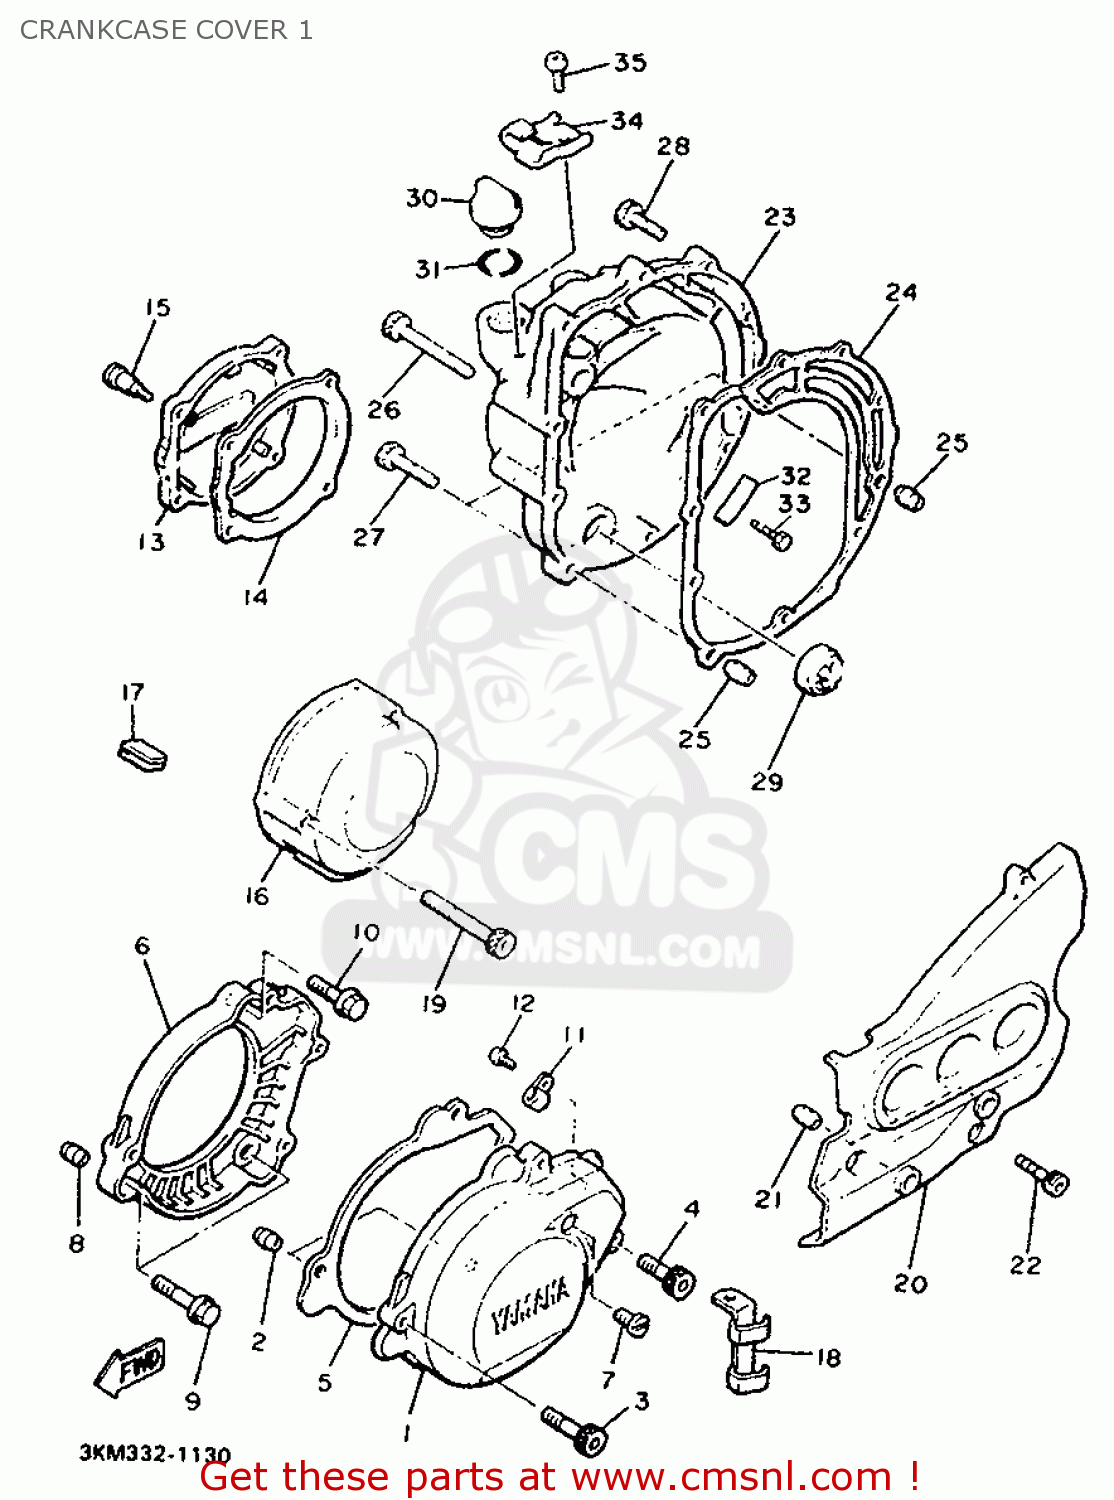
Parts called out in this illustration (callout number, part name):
01	COVER, GENERATOR
02	P1N, DOWEL
03	BOLT
04	BOLT
05	GASKET, CRANKCASE COVER 1 (MCA)
06	COVER, GENERATOR 2
07	PLUG, STRAIGHT SCREW(3KM)
08	P1N, DOWEL
09	BOLT, WASHER BASED(3KM)
10	BOLT, WASHER BASED(3KM)
11	CLAMP(3KM)
12	SCREW PAN HEAD
13	COVER, OIL PUMP 2
14	RING, RUBBER
15	BOLT 1
16	COVER, GENERATOR
17	GROMMET(3KM)
18	CLAMP(3LT)
19	BOLT
20	COVER, CRANKCASE 1
21	PIN, DOWEL
22	BOLT
23	COVER, CRANKCASE 2
24	GASKET, CRANKCASE COVER 2 (MCA)
25	PIN, DOWEL
26	BOLT
27	BOLT
28	BOLT, HEXAGON SOCKET HEAD(1VJ)
29	GAUGE, LEVEL
30	PLUG, OIL
31	O-RING(1KT)
32	COVER, OIL PUMP
33	BOLT(2VY)
34	HOLDER, CLUTCH CABLE
35	SCREW,PAN HEAD
